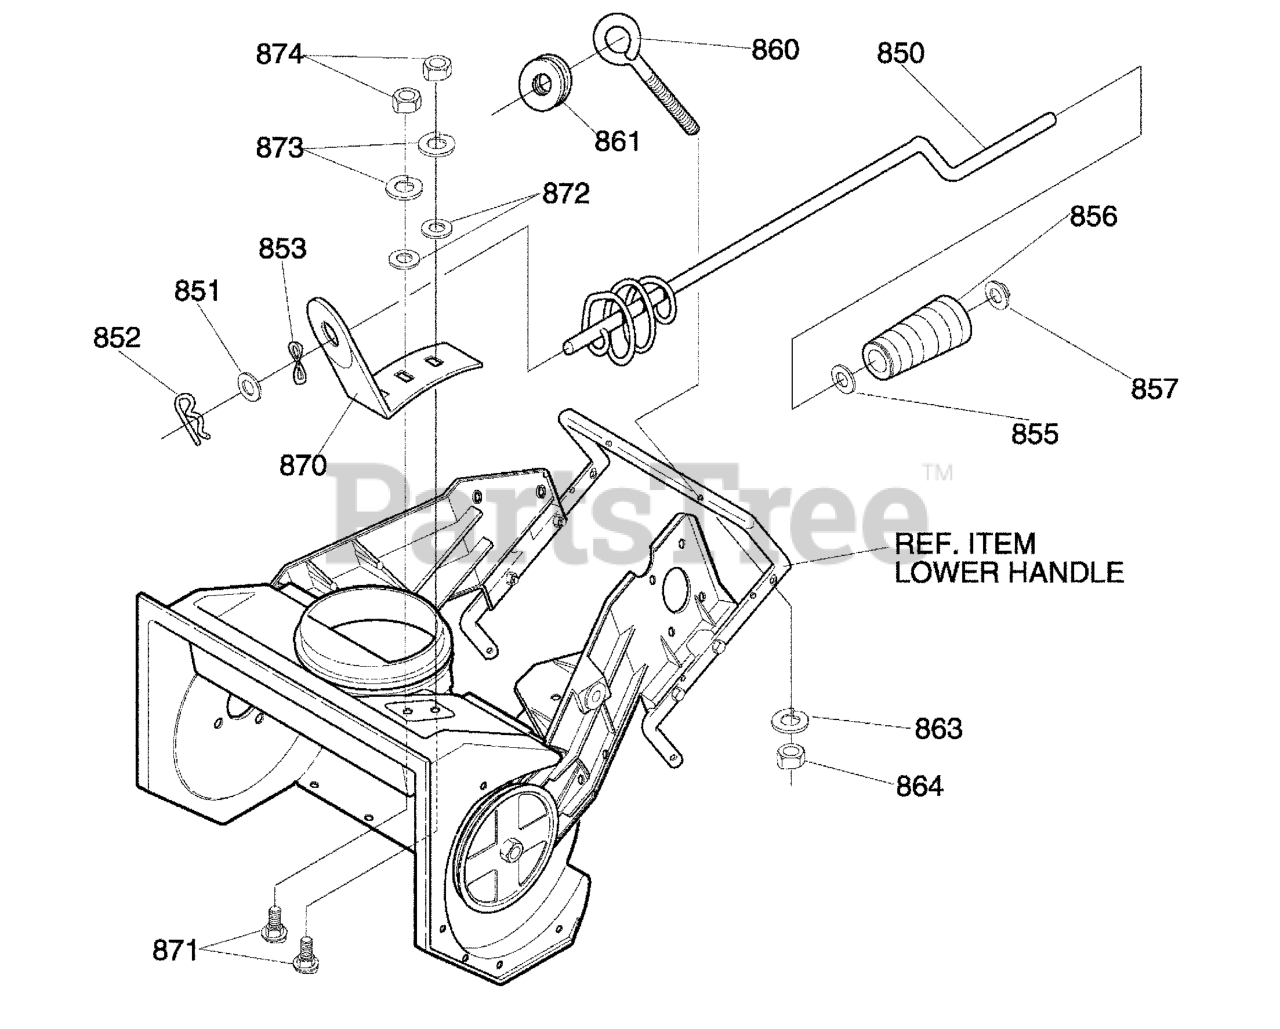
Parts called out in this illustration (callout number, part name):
850	ROD, ASSY UPPER CHUTE CONTROL
851	WASHER, FLAT .406X.81X.066
852	PIN, COTTER .094 DIAX1.00LG
853	WASHER, CURVED SPRING
855	WASHER, FLAT .406X.81X.066
856	KNOB, SLEEVE
857	NUT, PUSH
860	BOLT, EYE 3/8-16X2.00
861	GROMMET, EYE BOLT
863	WASHER, MDSPTLK
864	NUT, 3/8-16 HEXJAM
870	BRACKET, CHUTE ROTATE
871	BOLT, 5/16-18X.75 CARR.
872	WASHER, FLAT .349X.69X.066
873	WASHER, HVSPTLK .328 x .60 x .09
874	NUT, 5/16-18 REGHEX
